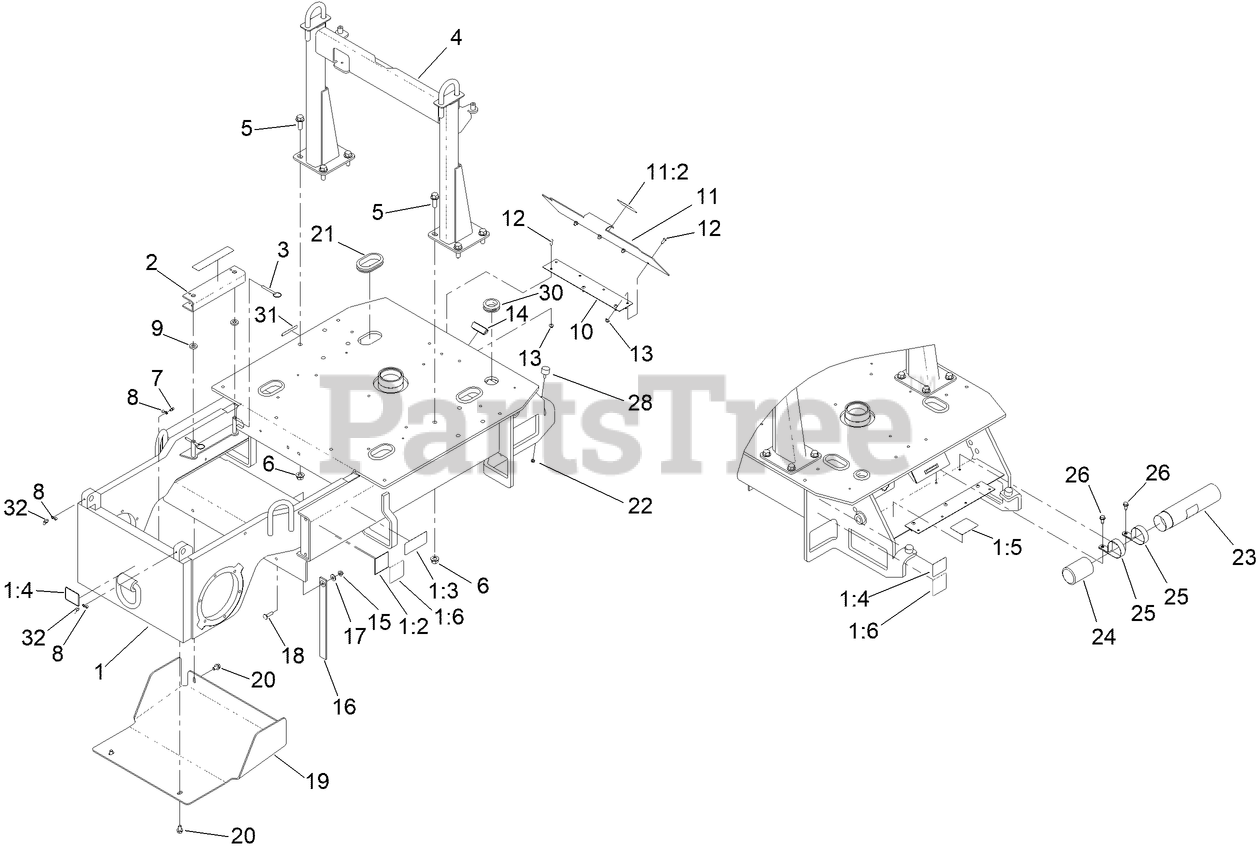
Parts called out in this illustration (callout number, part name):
1	FRAME ASM
1:2	DECAL-LIFT HERE
1:3	DECAL-WARNING, CRUSHING
1:4	DECAL-TIE DOWN
1:5	DECAL-WARNING, CHARGER
1:6	DECAL-FORKLIFT POCKET
2	CYLINDER LOCKING ASM
3	PIN-COTTERLESS
4	FRAME LIFT ASM-WELDED
5	SCREW-HHF
6	NUT-LOCK
7	FITTING-GREASE
8	CAP-PLUG
9	WASHER-NEOPRENE
10	HINGE-HOOD
11	COVER-CABLE
11:2	DECAL-BATTERY CHARGER
12	SCREW-HSBH
13	NUT-HF
14	MAGNET
15	NUT-HF, NI
16	STRAP, STATIC
17	WASHER-FLAT
18	SCREW-CARR
19	PLATE-SKID
20	SCREW-HWHTF
21	GROMMET
22	NUT-LOCK, NI
23	TUBE-MANUAL
24	CAP-HOUSING
25	CLAMP-R
26	SCREW-HWHTF
28	BUMPER
30	GROMMET
31	DECAL-WARNING
32	FITTING-LUBE, 45 DEG
